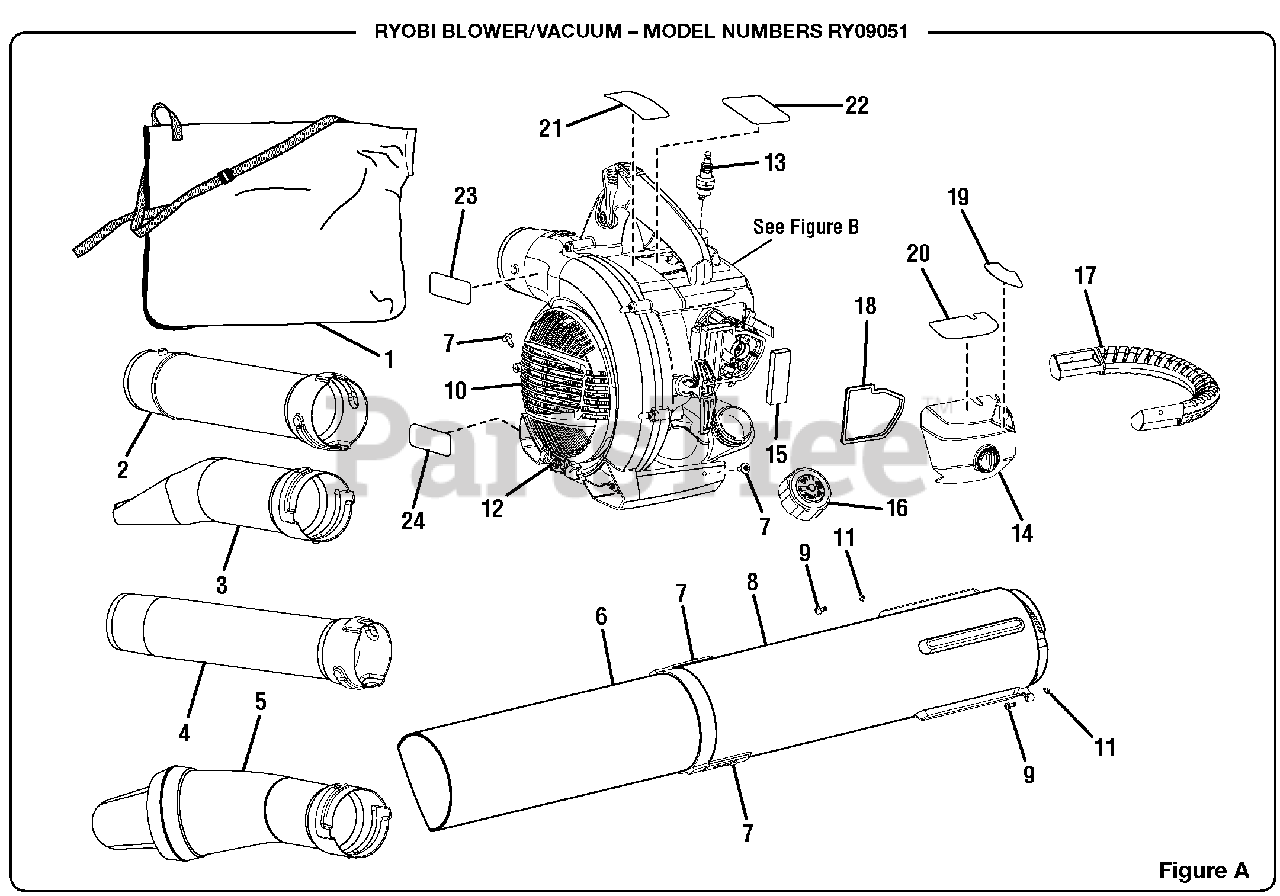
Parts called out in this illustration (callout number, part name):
1	Vacuum bag w/shoulder strap
2	Upper blower tube
3	High velocity nozzle w/leaf scraper
4	Sweeper nozzle
5	Vacuum bag adaptor
6	Lower vacuum tube
7	Vacuum tube screw (10-14 x 1/2 in.)
8	Upper vacuum tube
9	Screw (1/4-20 x 3/4 in.)
10	Vacuum door
12	Vacuum door spring
13	Spark plug (RCJ6Y)
14	Air filter cover
16	Fuel cap assembly
17	Vacuum handle
18	Air Box Gasket
19	Choke label
20	Starting label
21	Warning label
22	Logo label (small)
23	Logo label (large)
24	Combustion Label
